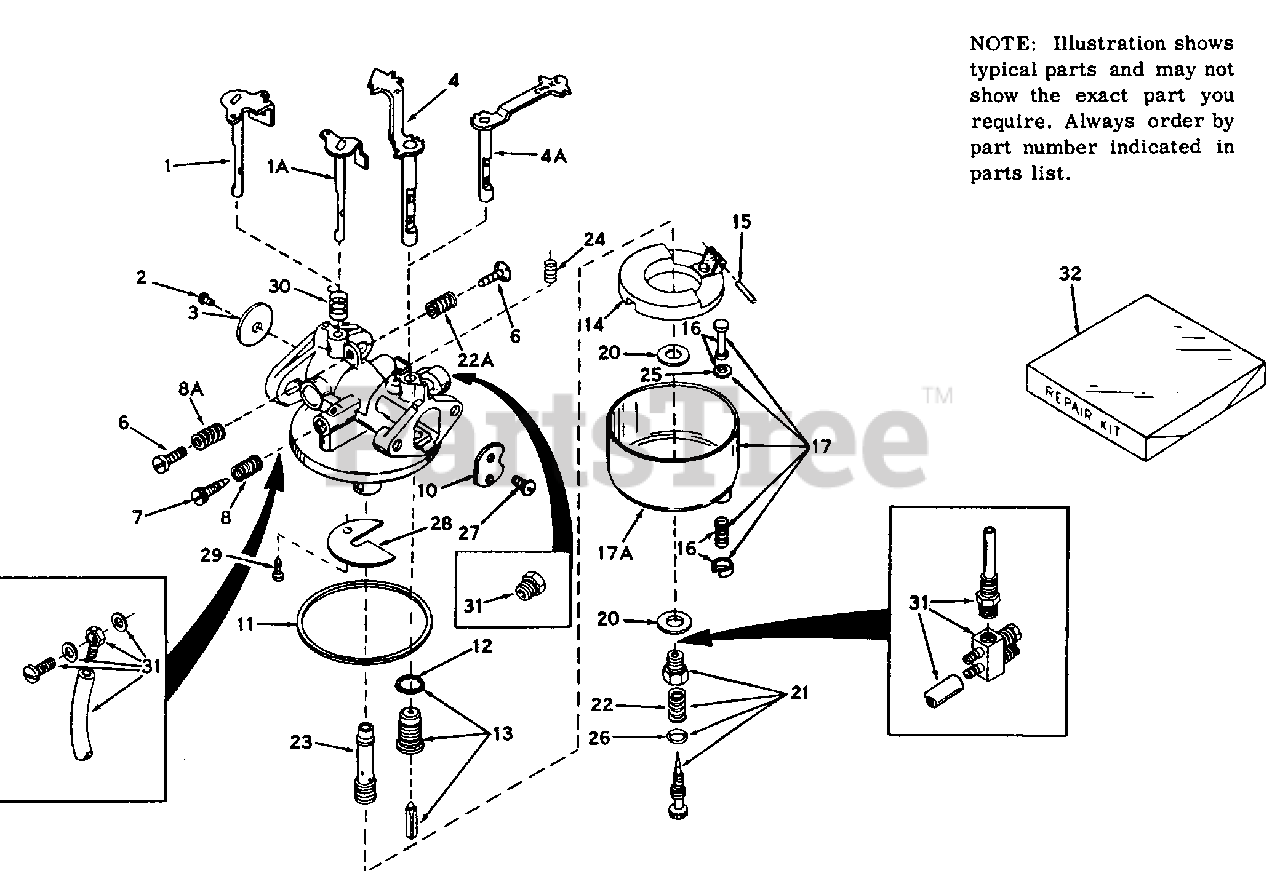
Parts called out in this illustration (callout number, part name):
1A	Throttle Shaft & Lever Assembly
2	Screw
3	Throttle Shutter
4	Choke Shaft & Lever Assembly
6	Throttle Adjusting Screw
8A	Adjusting Needle Spring
10	Choke Shutter
11	Bowl-to-Body Gasket
16	Bowl Drain Stem Assembly (Incl. 25)
17	Bowl & Drain Assembly (Incl. 16)
20	Bowl-to-Body Gasket
24	Choke Stop Spring
25	Drain Stem Gasket
27	Screw
30	Throttle Return Spring
31	L-P Gas Conversion Kit
